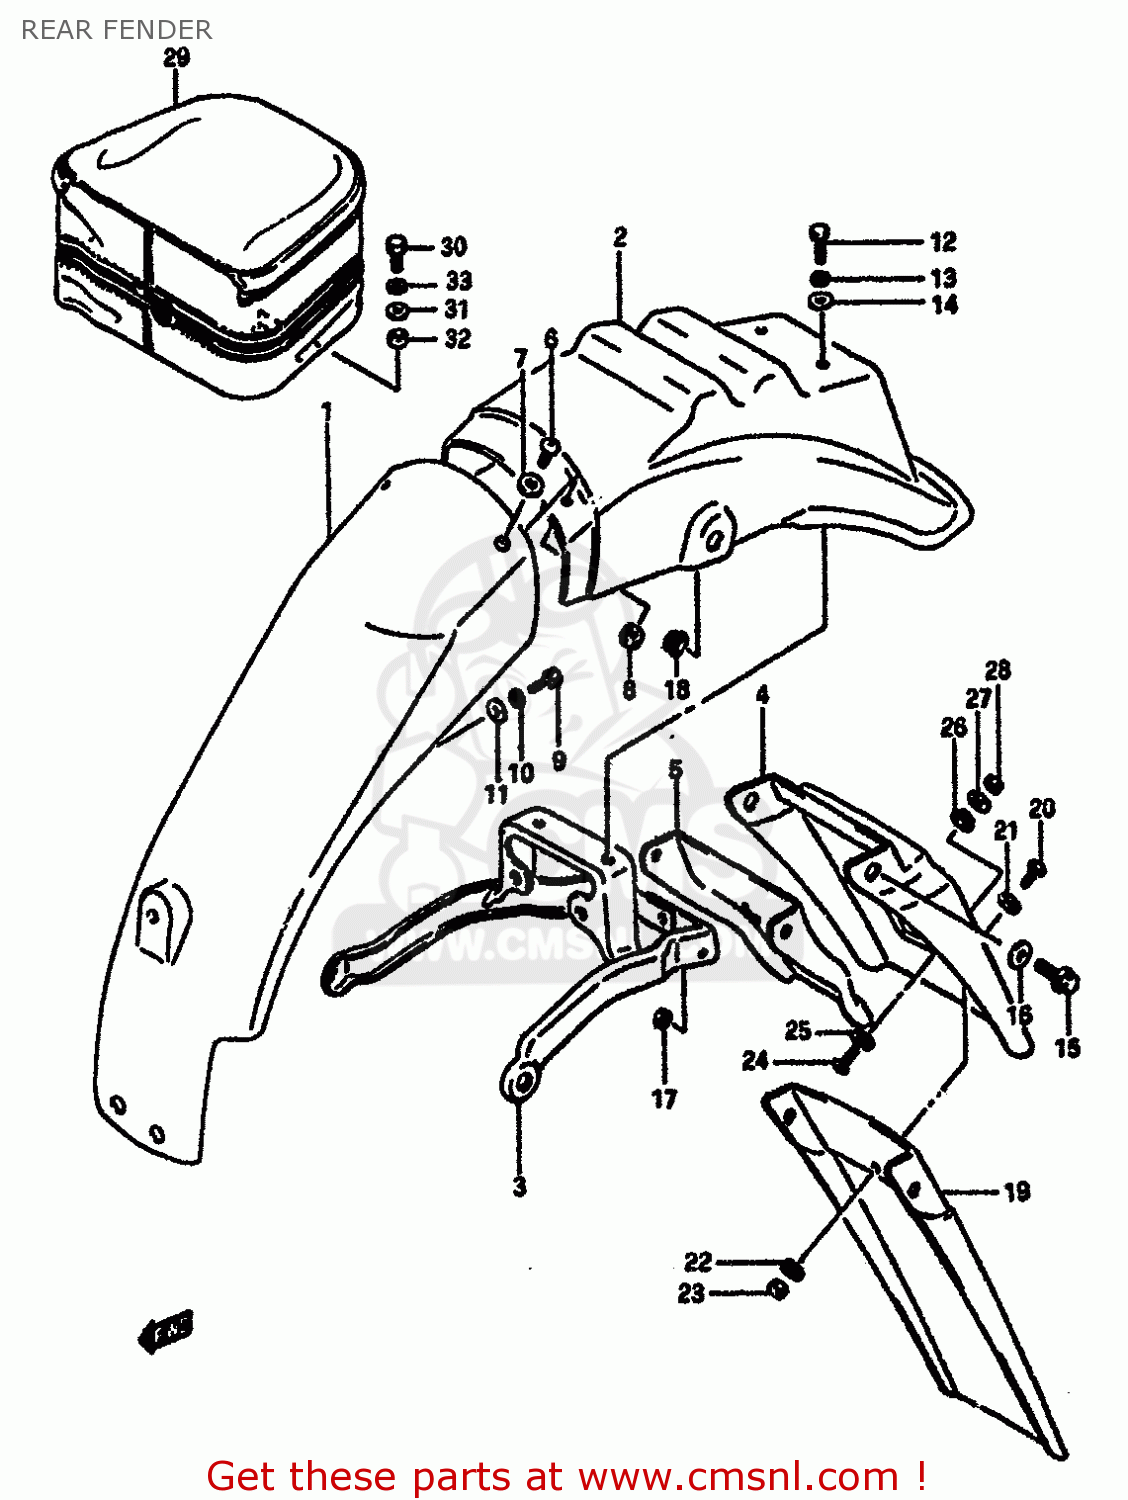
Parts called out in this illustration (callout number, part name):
1	BODY,REAR FENDER,FRONT
2	FENDER,REAR
3	REINFORCEMENT,REAR FENDER
4	EXTENSION
5	REINFORCEMENT,REAR FENDER EXTENSION
6	SCREW, FRONT & REAR
7	WASHER
8	NUT 8MM
9	BOLT 6X16
10	WASHER,LOCK
11	WASHER
12	BOLT
13	WASHER,LOCK
14	WASHER
15	BOLT
16	WASHER
17	NUT
18	NUT
19	MUD GUARD
20	SCREW 6X12
21	WASHER(6.5X16X1.2)
22	WASHER,LOCK
23	NUT
24	SCREW
25	WASHER
26	WASHER
27	WASHER
28	NUT
29	BAG ASSY,SEAT TAIL (BLUE/WHITE)
30	BOLT
31	WASHER
32	SPACER
33	WASHER,LOCK
